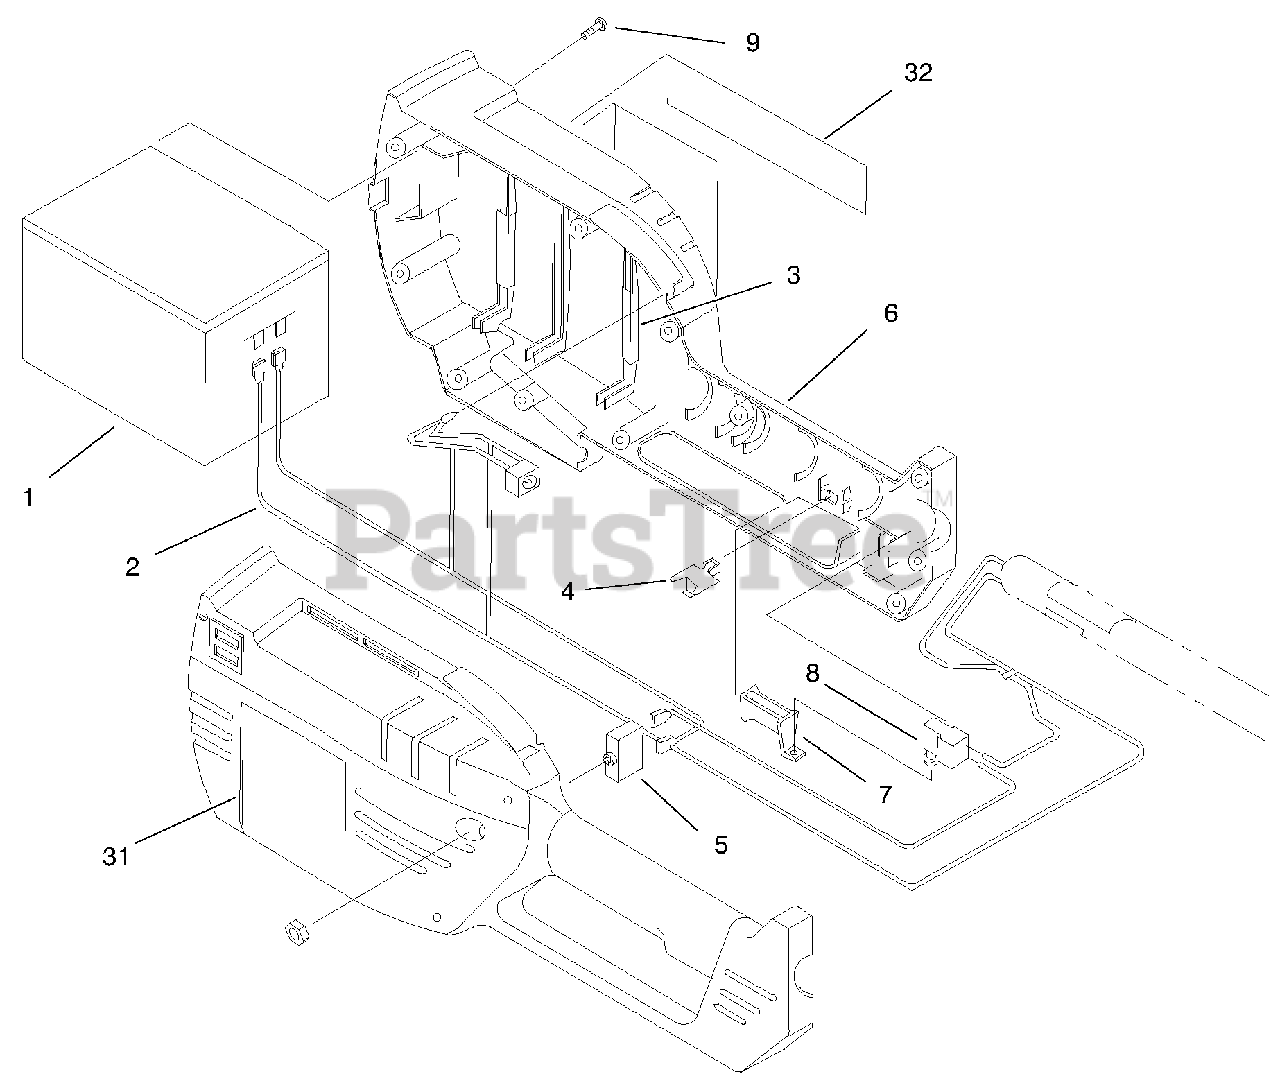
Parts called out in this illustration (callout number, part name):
1	Battery
2	Wiring Harness Assembly
3	Battery Cushion Set
4	Safety Release Switch
5	Thermal Overload Switch
6	Battery Housing With Out Decals
7	Trigger
9	Housing Screw
31	Decal-Toro, Housing
32	Decal-Recycle Battery
